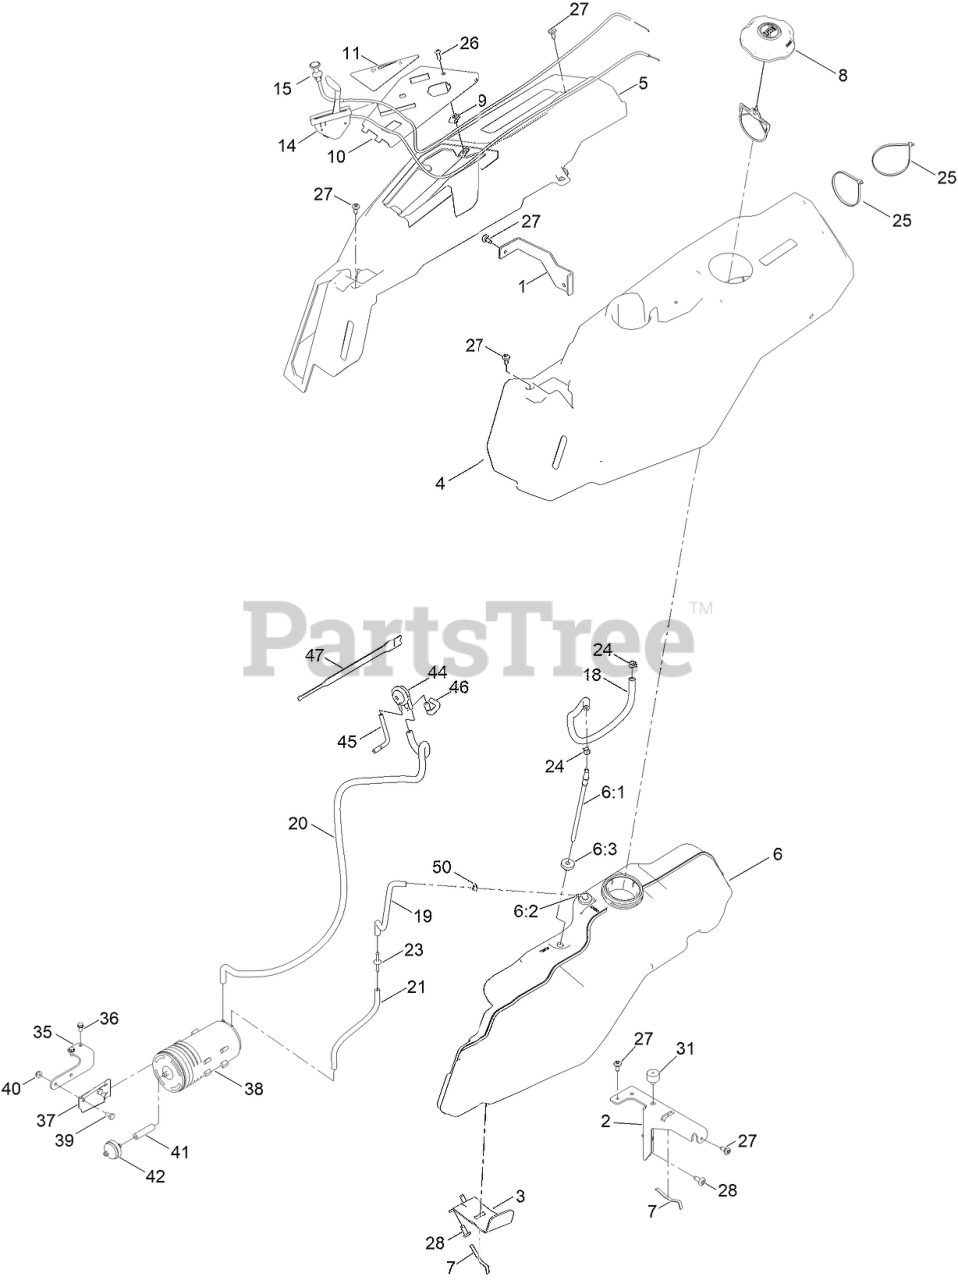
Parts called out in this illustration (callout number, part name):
1	BRACKET-POD
2	SUPPORT-POD, LH
3	SUPPORT-TANK, FUEL
4	POD-LH
5	POD-RH, MYRIDE
6	TANK-FUEL ASM
6:1	CONNECTOR-ELBOW, 90 DEG
6:2	FITTING-ELBOW 90
6:3	BUSHING
7	SPRING
8	CAP-FUEL, RATCHETING
10	PANEL - CONTROL
11	DECAL-PANEL, CONTROL
14	CABLE-THROTTLE
15	CABLE-CHOKE
18	HOSE-FUEL
19	HOSE-FUEL
20	HOSE-FUEL
21	HOSE-FUEL
23	ADAPTER ORIFICE
24	CLAMP-HOSE
25	TIE-CABLE
26	SCREW-PRH
27	SCREW-SHOULDER
31	BUMPER-GROMMET
35	BRACKET-CANISTER, CARBON
36	SCREW-HWH
37	BRACKET-CANISTER, CARBON
38	CANISTER-CARBON, 800CC
39	SCREW-HH
40	NUT-HF
41	HOSE-FUEL
42	FILTER-FUEL, INLINE
44	VALVE-CONTROL, VACUUM
45	HOSE-VENT, FORMED
46	HOSE-VENT, FORMED
47	STRAP-VELCRO, CABLE TIE
50	CLAMP-HOSE
